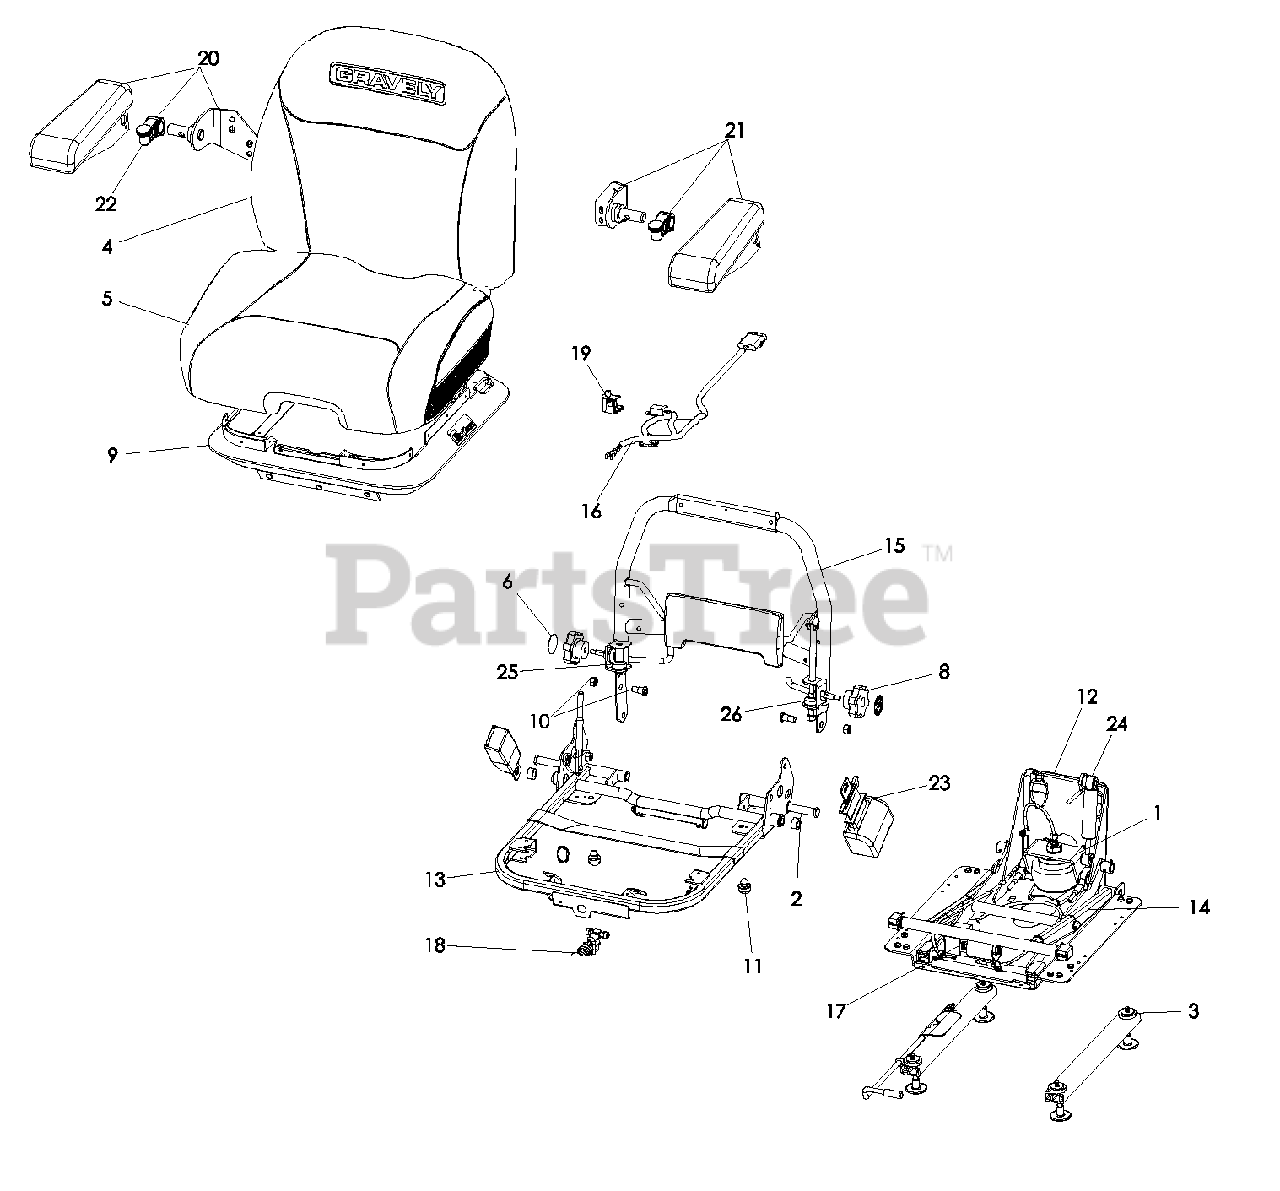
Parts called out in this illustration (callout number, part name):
1	KIT, SPRING AND SADDLE
2	KIT, SHAFT/BEARING
3	KIT, SLIDE
4	KIT, BACK CUSHION
5	KIT, SEAT CUSHION
6	KIT, LABEL
7	KIT, BACK PANEL
8	KIT, KNOB
9	KIT, BOOT
10	KIT, PIVOT BOLT
11	KIT, BUMPER
12	KIT, SUSPENSION BASE WELDMENT
13	KIT, SEAT FRAME WELDMENT
14	KIT, LINKAGE ASSEMBLY
15	KIT, BACK FRAME WELDMENT
16	KIT, WIRE HARNESS
17	KIT, COMPRESSOR
18	KIT, AIR VALVE
19	KIT, OPS SWITCH
20	KIT, RH ARMREST ASSEMBLY
21	KIT, LH ARMREST ASSEMBLY
22	KIT, ARMREST STOP
24	KIT, SHOCK ABSORBER
25	KIT, GEAR
26	KIT, GEAR
